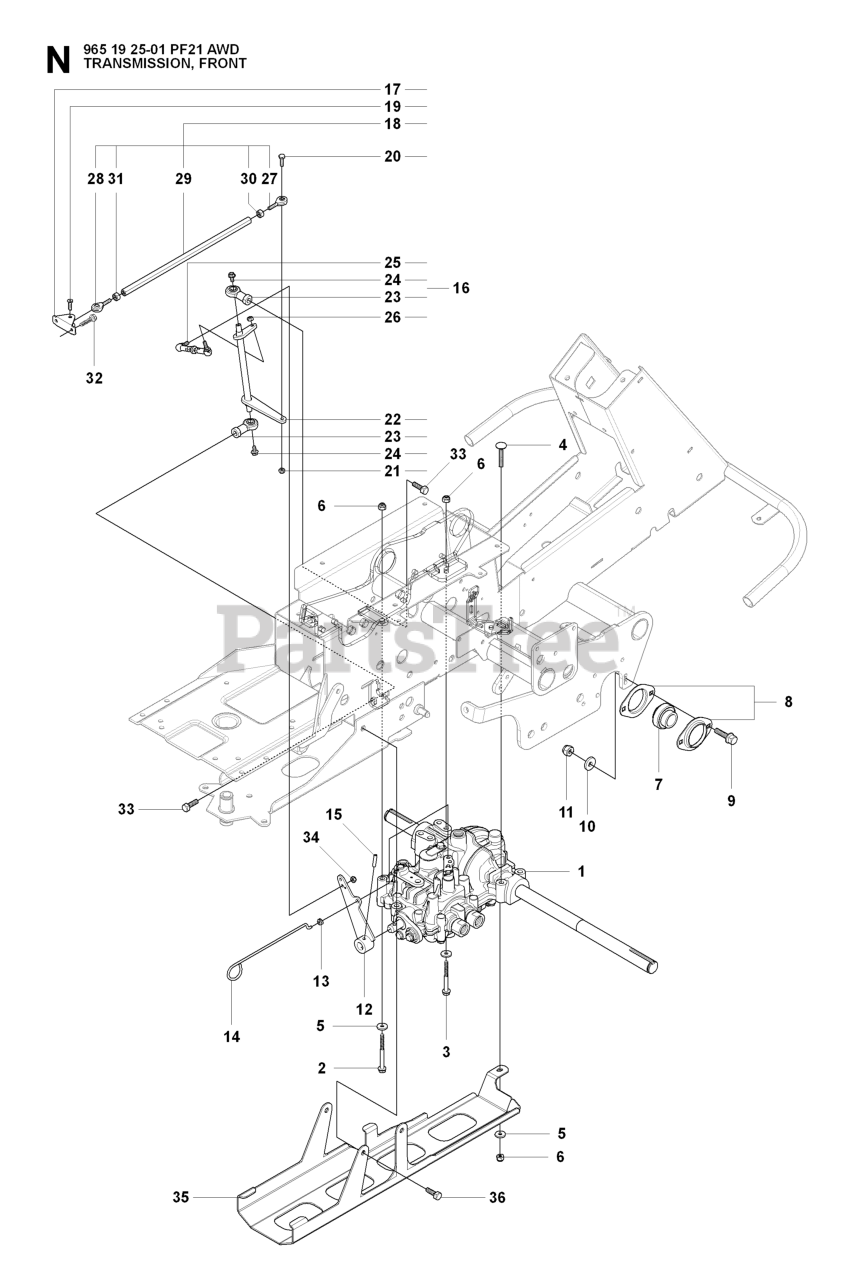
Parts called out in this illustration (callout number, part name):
5	WASHER BRB 8.4X17
6	LOCKNUT M8
8	BEARING HOUSING
9	BOLT
10	WASHER BRB 8.4X17
11	LOCKNUT M8
13	FUEL TANK BUSHING
21	NUT FLANGE - M6
24	SCREW EHHFM
25	ADJUSTING ROD
26	NUT FLANGE - M6
33	Screw M10x25
34	LOCKNUT M6
